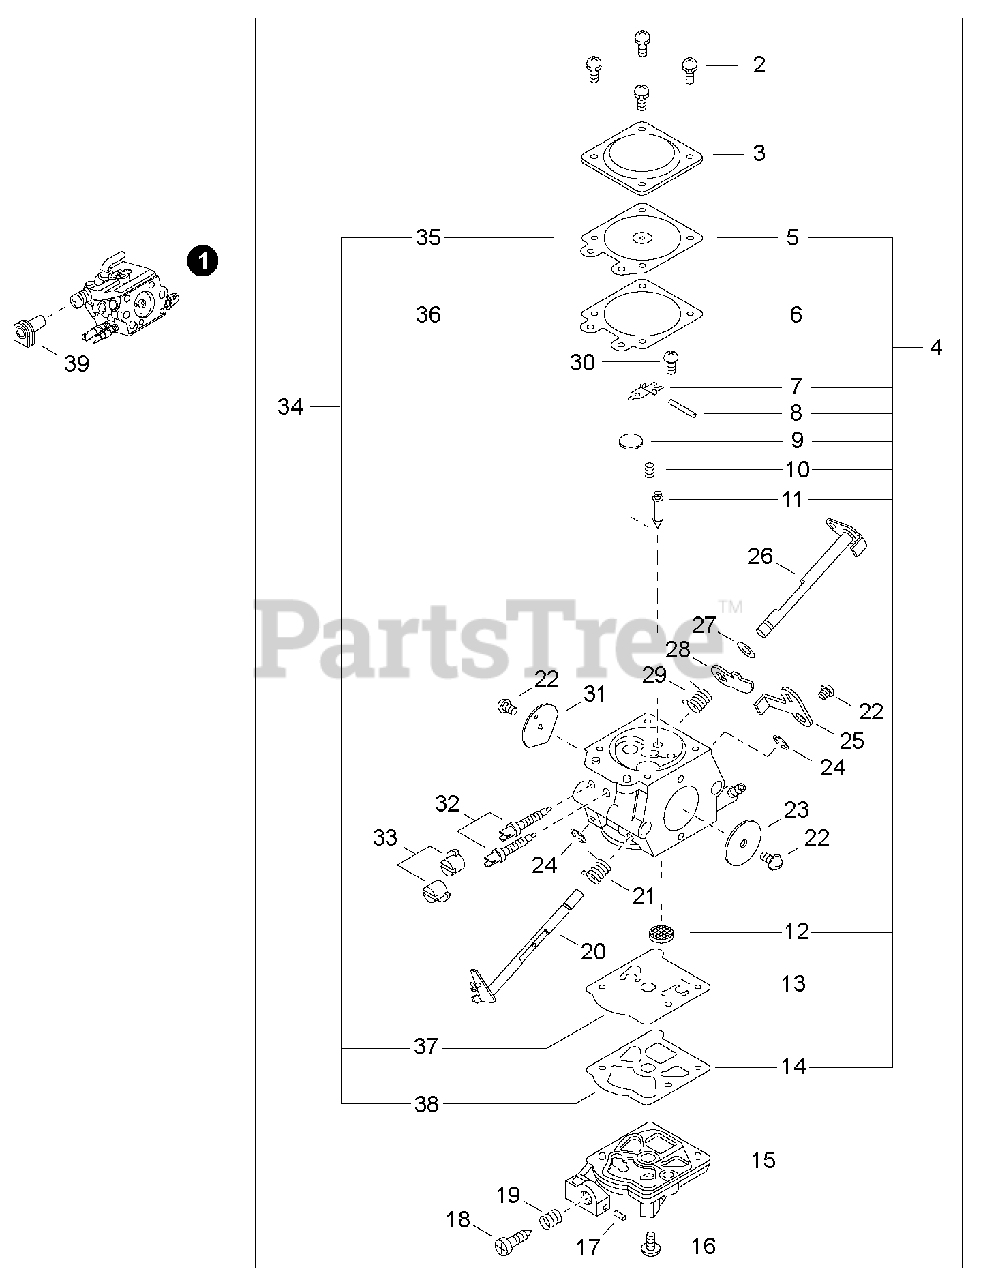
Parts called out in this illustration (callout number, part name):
1	CARBURETOR WT-594
3	COVER, METERING
4	REPAIR KIT
5	DIAPHRAGM, METERING
6	GASKET, METERING
7	LEVER, METERING
8	PIN, METERING LEVER
9	PLUG, WELCH
10	SPRING, METERING LEVER
11	VALVE, INLET NEEDLE
12	STRAINER
13	DIAPHRAGM, PUMP
14	GASKET, PUMP
15	COVER, PUMP
16	SCREW, PUMP COVER
18	SCREW, IDLE ADJUST
19	SPRING, IDLE ADJUST
20	SHAFT, THROTTLE
21	SPRING, THROTTLE RETURN
23	VALVE, THROTTLE
24	RING, RETAINING
25	LEVER, THROTTLE
26	SHAFT, CHOKE
28	LEVER, FAST IDLE
29	SPRING, CHOKE RETURN
30	SCREW, METERING LEVER PIN
31	VALVE, CHOKE
32	NEEDLE - MIXTURE
33	CAP, LIMITER
34	DIAPHRAGM/GASKET KIT
35	DIAPHRAGM, METERING
36	GASKET, METERING
37	DIAPHRAGM, PUMP
38	GASKET, PUMP
